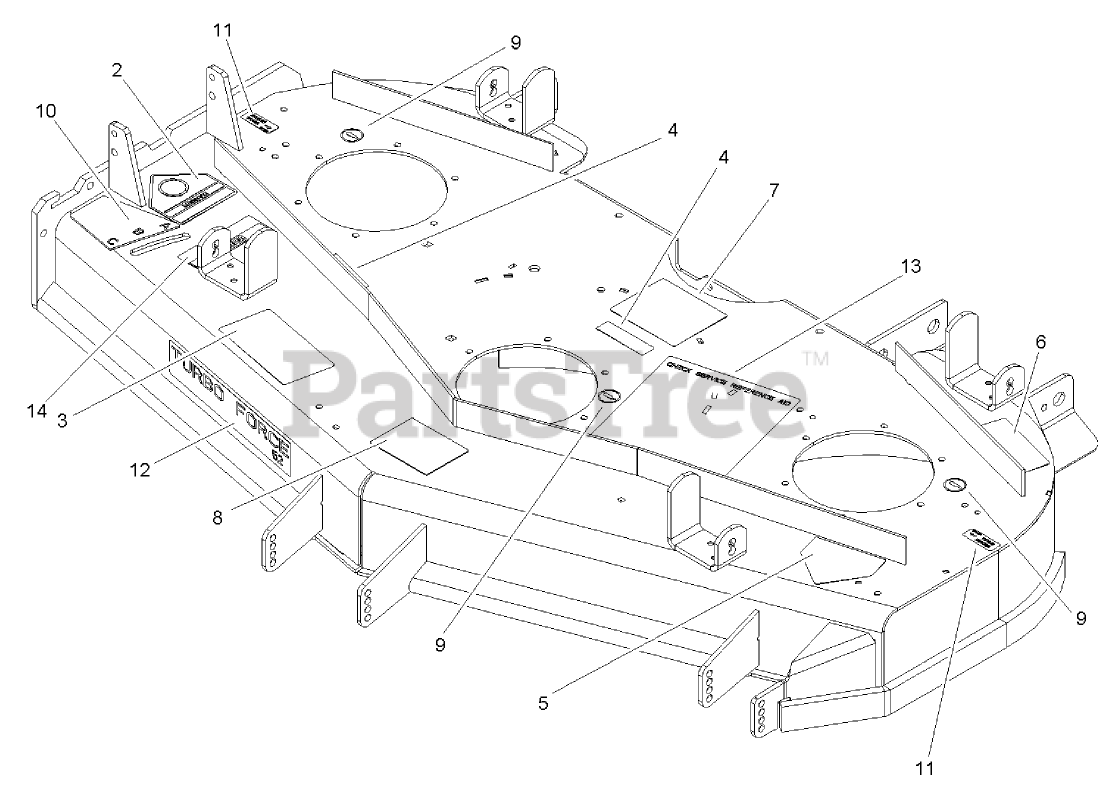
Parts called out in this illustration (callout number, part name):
2	DECAL-DANGER
3	DECAL-DANGER, THROWN OBJECT
4	DECAL-COVER, MISSING
5	DECAL-DANGER
6	DECAL-TORQUE
7	Decal-Routing, Belt
8	DECAL-SCALP, ANTI
9	DECAL-GREASE
10	DECAL-ADJUSTMENT, BAFFLE
11	Decal-Grease
13	Decal-Service, Check
14	DECAL-WARNING
